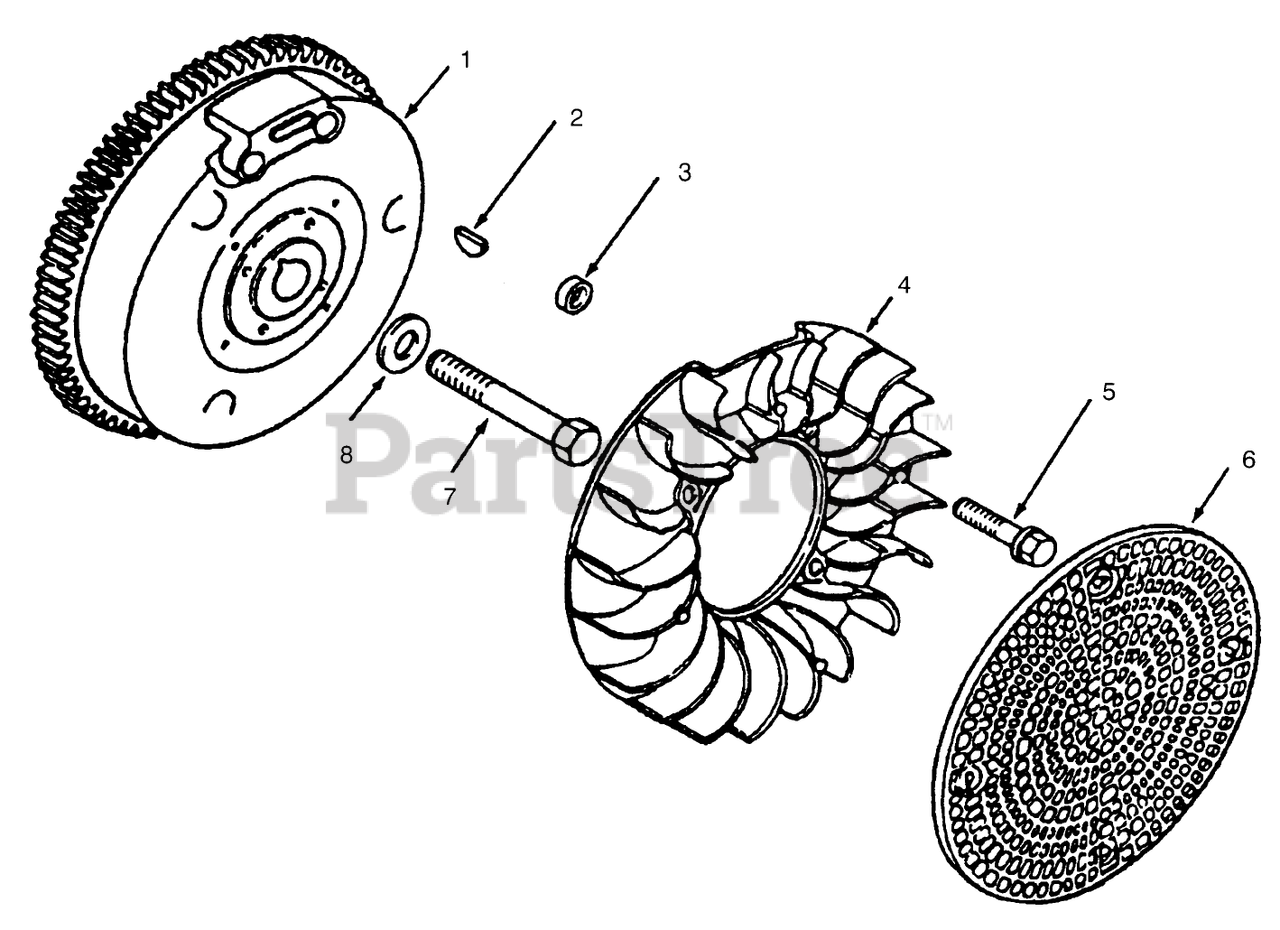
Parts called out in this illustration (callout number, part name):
1	KOHLER 47-025-53
2	KOHLER X-46-3
3	KOHLER 25-089-02
4	KOHLER 25-157-01
5	KOHLER 25-086-21
6	KOHLER 25-162-01
7	KOHLER 25-086-24
8	KOHLER 52-468-15
